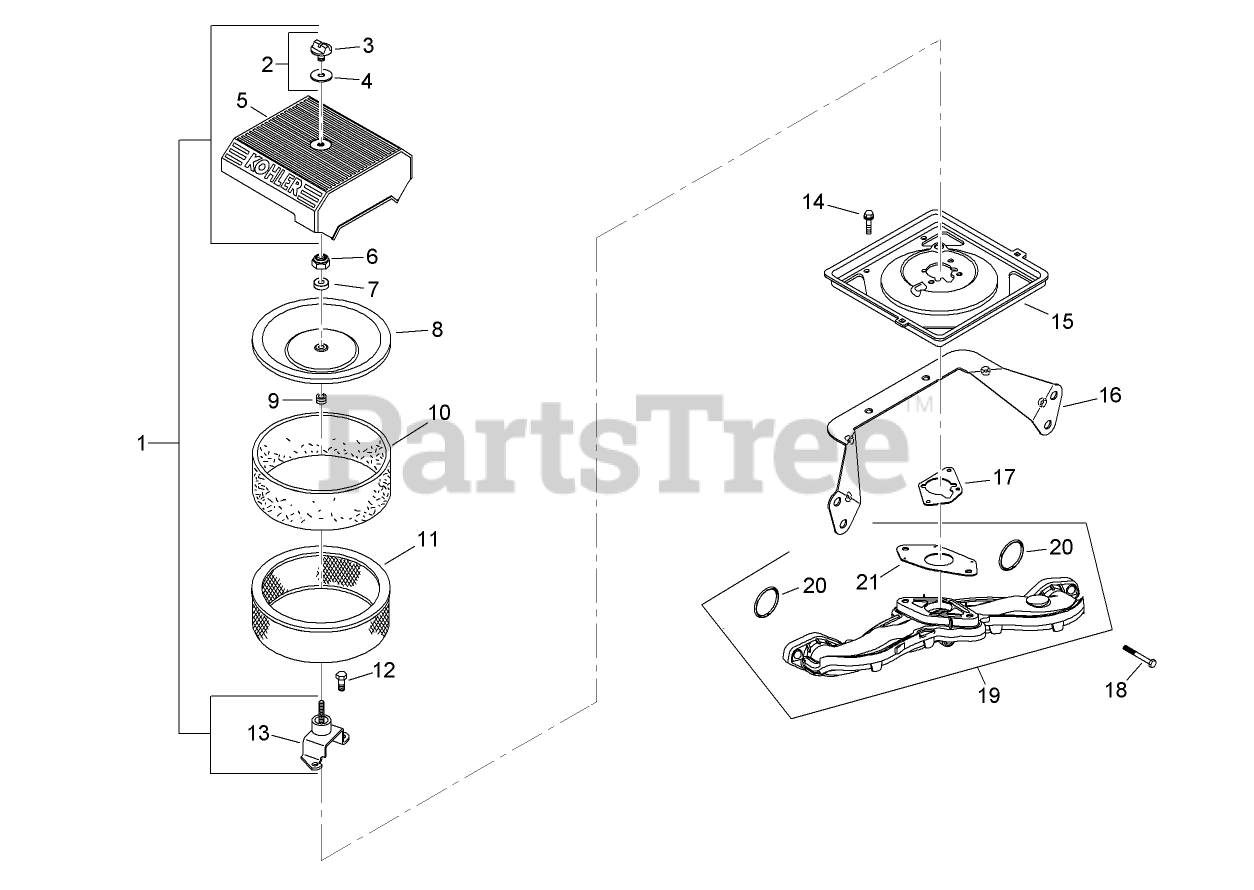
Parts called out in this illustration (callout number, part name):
1	Air Cleaner Cover Kit (INCLUDES 2-5, 13)
2	KNOB W/SEAL KIT
3	KNOB-COVER
4	O-RING
5	Cover-Cleaner, Air
6	Nut-Lock (M6X1.0)
7	Spacer
8	COVER-AIR CLEANER, INNER
9	Seal
10	PRE-CLEANER
11	ELEMENT-FILTER, AIR
12	SCREW-FLANGE, THREAD FORMING (M6X1.0X16)
13	Bracket-Base, Air Cleaner
14	SCREW-HHFTF (M5X.80X10)
15	BASE-CLEANER, AIR
16	BRACKET-BASE, AIR CLEANER
17	GASKET-BASE, AIR CLEANER
18	SCREW-FLANGE (M6X1.0X40)
19	Intake Manifold ASM
20	O RING-PORT, INTAKE
21	GASKET-CARBURETOR
